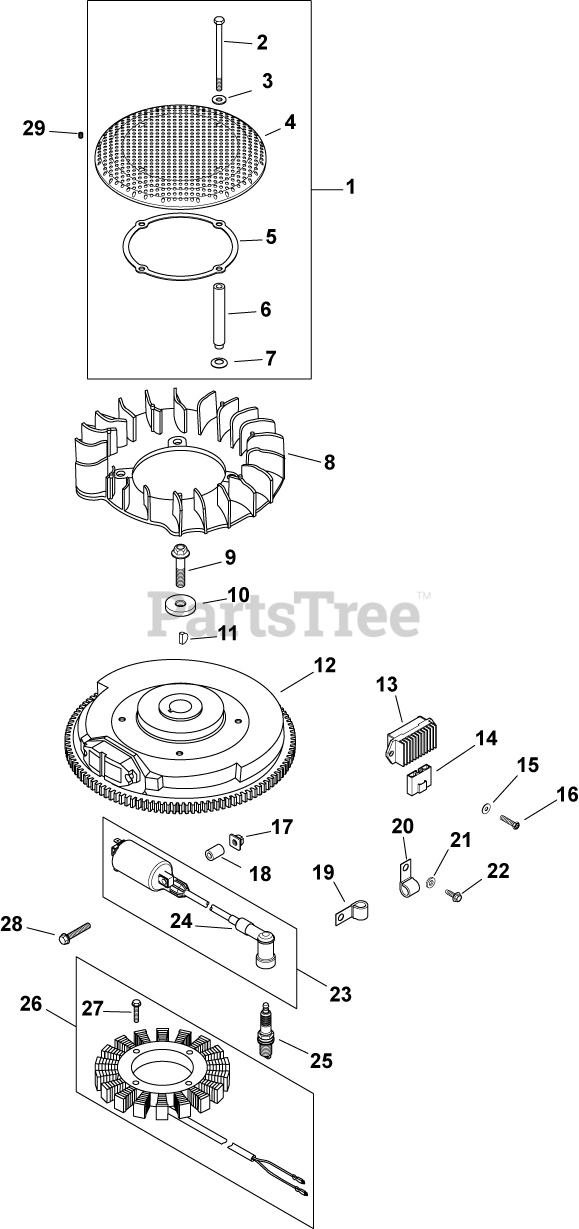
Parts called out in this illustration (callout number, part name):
1	KIT, CHOPPER SCREEN
2	SCREW, CAP M6X1.0X99.5
3	WASHER, FLAT 1/4" (O.D. 5/8")
4	SCREEN, GRASS
5	RING, SUPPORT USE 25 141 08-S
7	WASHER, SPRING 10 MM
9	SCREW, FLG M10X1.5X45 - (#25086361S)
10	WASHER, FLAT 13/32"
11	KEY, 3/16" X 5/8"
12	FLYWHEEL - (#2402530S)
13	REG-RECTIFIER (25 AMP)-USE 25 403 21-S
14	CONNECTOR, BODY (KM)-USE 25 155 41-S
15	WASHER, FLAT 3/16"
16	SCREW, PHL HD #11-16X7/8"
17	NUT, PLASTIC (KM)-USE 25 100 37-S
19	CLIP, TUBE & WIRING (KM)
20	CLAMP, INSULATED
21	WASHER, FLAT 7/32"
22	SCREW,FLG THD FRM M5X0.8X16-(#25086398S)
23	COIL, IGNITION
24	BOOT, SPARK PLUG
25	PLUG, SPARK (STD)
26	KIT, 25 AMP STATOR ASSY.
27	SCREW, WSH HD TAP #10-24X1"
28	SCREW,WSH HD TAP 1/4-14X1 1/2"
29	SCREW, SKT SET #10-24X1/4"
2402523-S	KIT, FLYWHEEL ASSEMBLY
